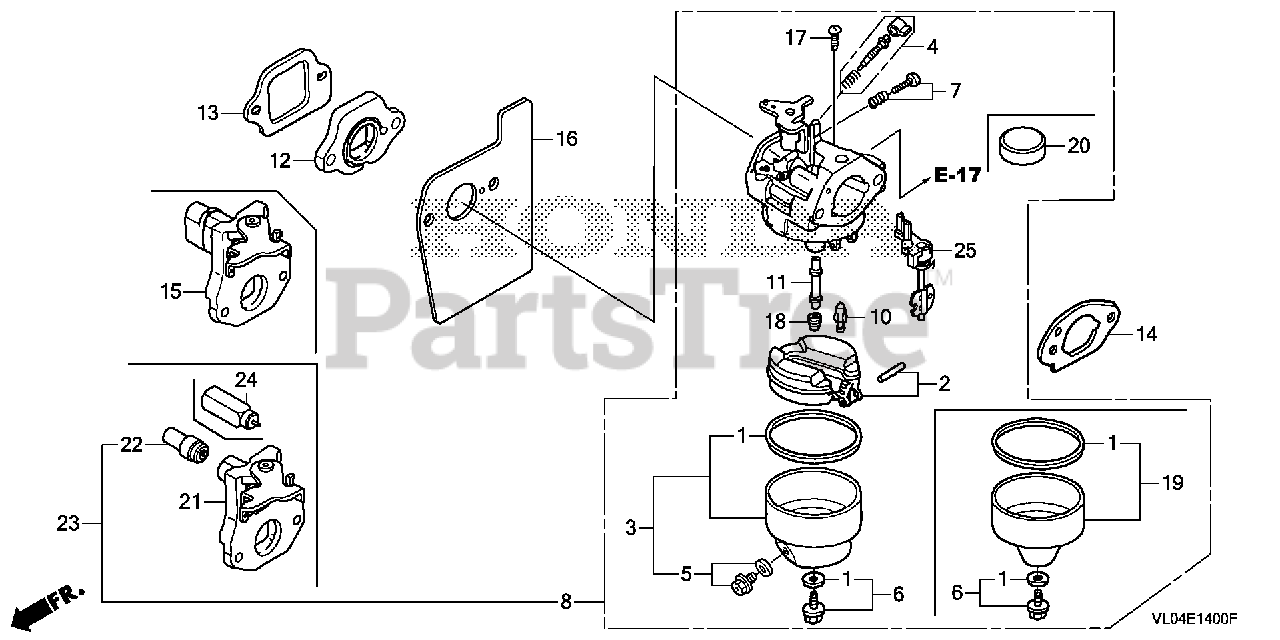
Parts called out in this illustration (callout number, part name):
1	GASKET SET
2	FLOAT SET
4	SCREW SET (CARBURETOR NO.)
6	SCREW SET
7	SCREW SET (THROTTLE STOP) (CARBURETOR NO.)
8	CARBURETOR ASSY. (BB75J A)
10	VALVE, FLOAT (Honda Code 7934714). (CARBURETOR NO.)
11	NOZZLE, MAIN (CARBURETOR NO.)
13	GASKET, INSULATOR
14	GASKET, CARBURETOR (CHOKE SIDE)
16	GUIDE, AIR
17	SCREW, PAN (5X6)
18	JET, MAIN (#62) (Honda Code 0635482). (CARBURETOR NO.)
18	JET, MAIN (#60) (Honda Code 0635474). (CARBURETOR NO.)
18	JET, MAIN (#65) Use up to Engine SN BB30A D.
19	CHAMBER SET, FLOAT (CARBURETOR NO.)
20	CAP, CHOKE DUST (CARBURETOR NO.)
21	CONTROL ASSY., CHOKE
24	THERMO WAX ASSY.
